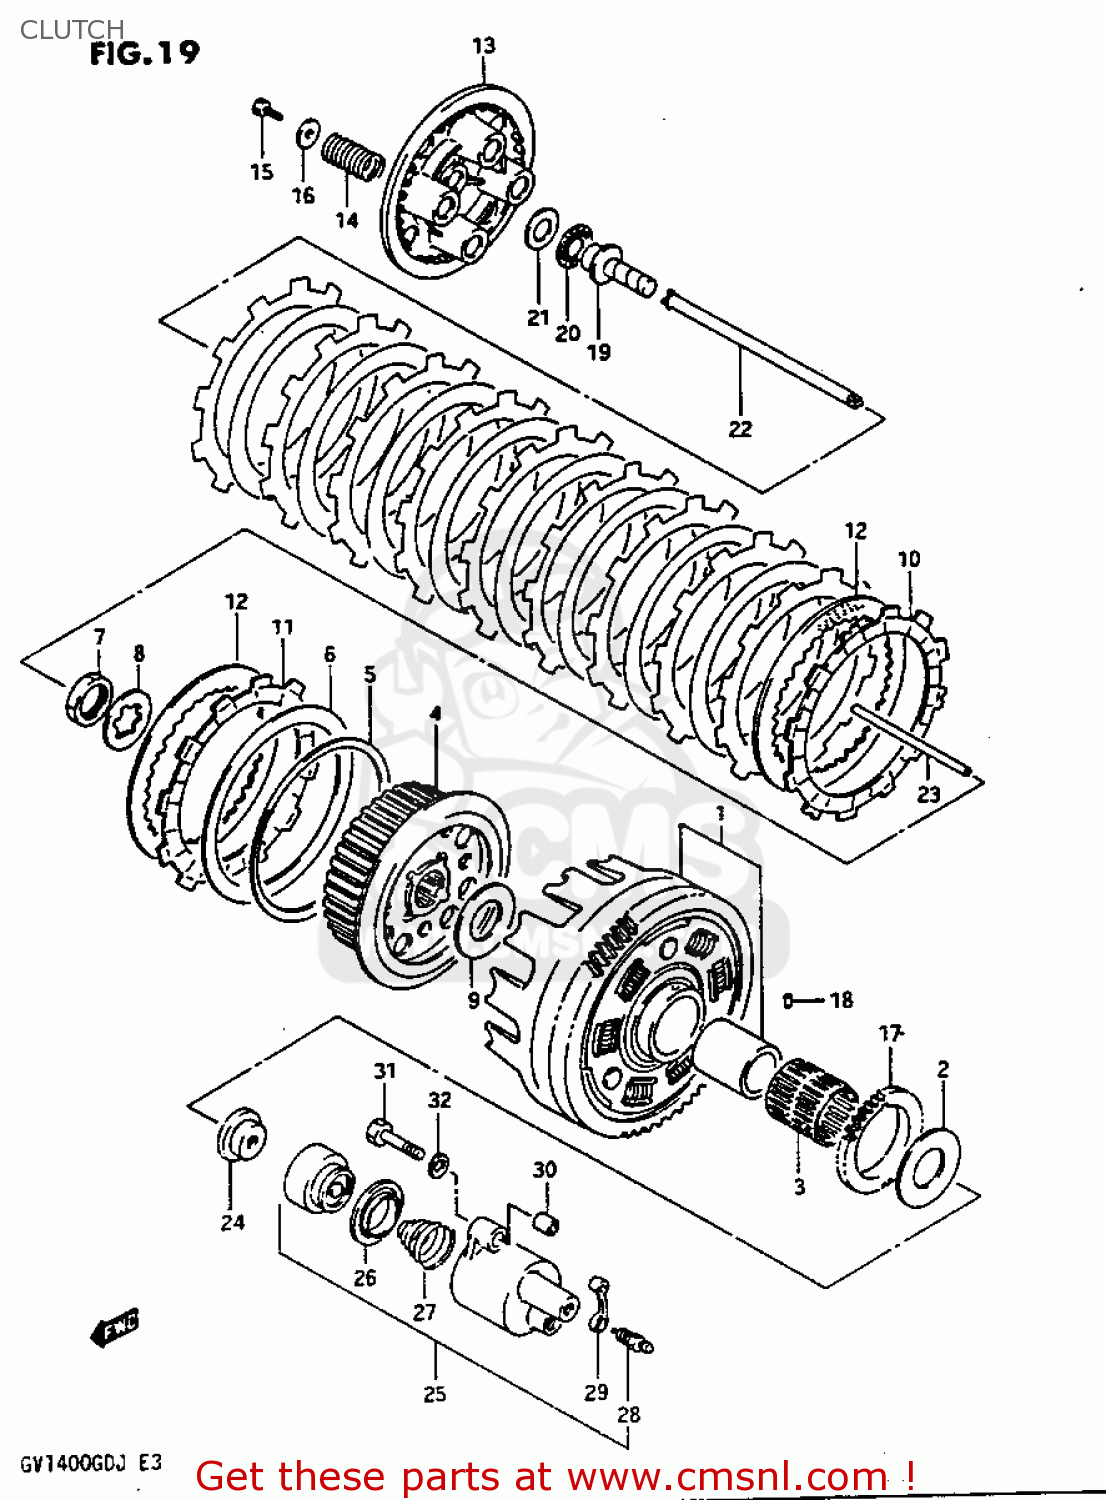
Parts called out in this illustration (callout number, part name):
1	GEAR ASSEMBLY,PRIMARY DRIVE
2	WASHER(25X54X2.5)
3	BEARING(35X40X39.8)
4	HUB COMP,CLUTCH SLEEVE
5	SEAT,WAVE WASHER(T:1.4)
6	WASHER
7	NUT
8	WASHER,LOCK
9	WASHER(25X50X2.5)
10	PLATE,CLUTCH DRIVE (NAS)
11	PLATE,CLUTCH DRIVE(T:3.5) (NAS)
12	PLATE,CLUTCH DRIVEN(T:1.6) (NAS)
13	DISC,CLUTCH PRESSURE
14	SPRING
15	BOLT
16	WASHER(6.5X20X1.6)
17	GEAR,OIL PUMP DRIVE
18	PIN(6X6)
19	PIECE,CLUTCH PUSH
20	BEARING(15X28X2)
21	WASHER(15.5X28X1)
22	ROD,CLUTCH PUSH
23	ROD,CLUTCH PUSH,L
24	SEAL,OIL(6X36X6)
25	CYLINDER,CLUTCH RELEASE
26	CUP,CLUTCH CYLINDER
27	SPRING,CLUTCH CYLINDER
28	BLEEDER
29	CAP,BLEEDER
30	PIN
31	BOLT ,6X35
32	WASHER,LOCK
